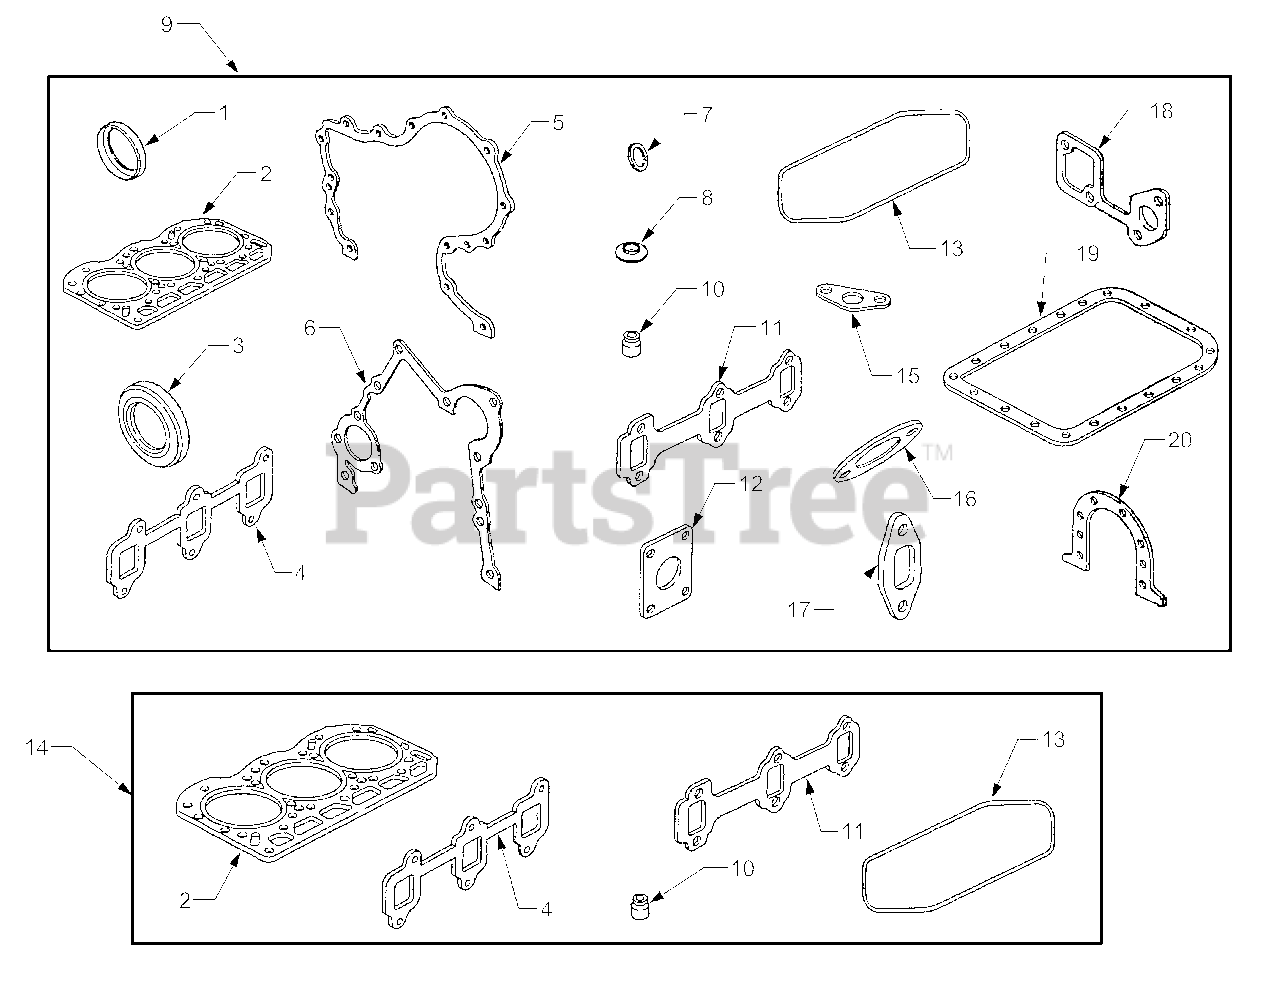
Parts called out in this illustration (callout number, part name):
1	Seal, Oil
2	Gasket, Cylinder Head
3	Seal, Oil
4	Gasket, Intake
5	Gasket, Gear Cover
6	Gasket, Gear Cover
7	Washer, Sealing
8	Washer, Sealing
9	Gasket Set
10	Seal, Valve
11	Gasket, Exhaust
12	Gasket, Exhaust
13	Gasket, Rocker Cover
14	Kit, Valve Overhaul
15	Gasket, Oil Pump Screen
16	Gasket, Outlet
17	Gasket, Inlet Housing
18	Gasket, Water Pump
19	Gasket, Oil Pan
20	Gasket, Retainer
